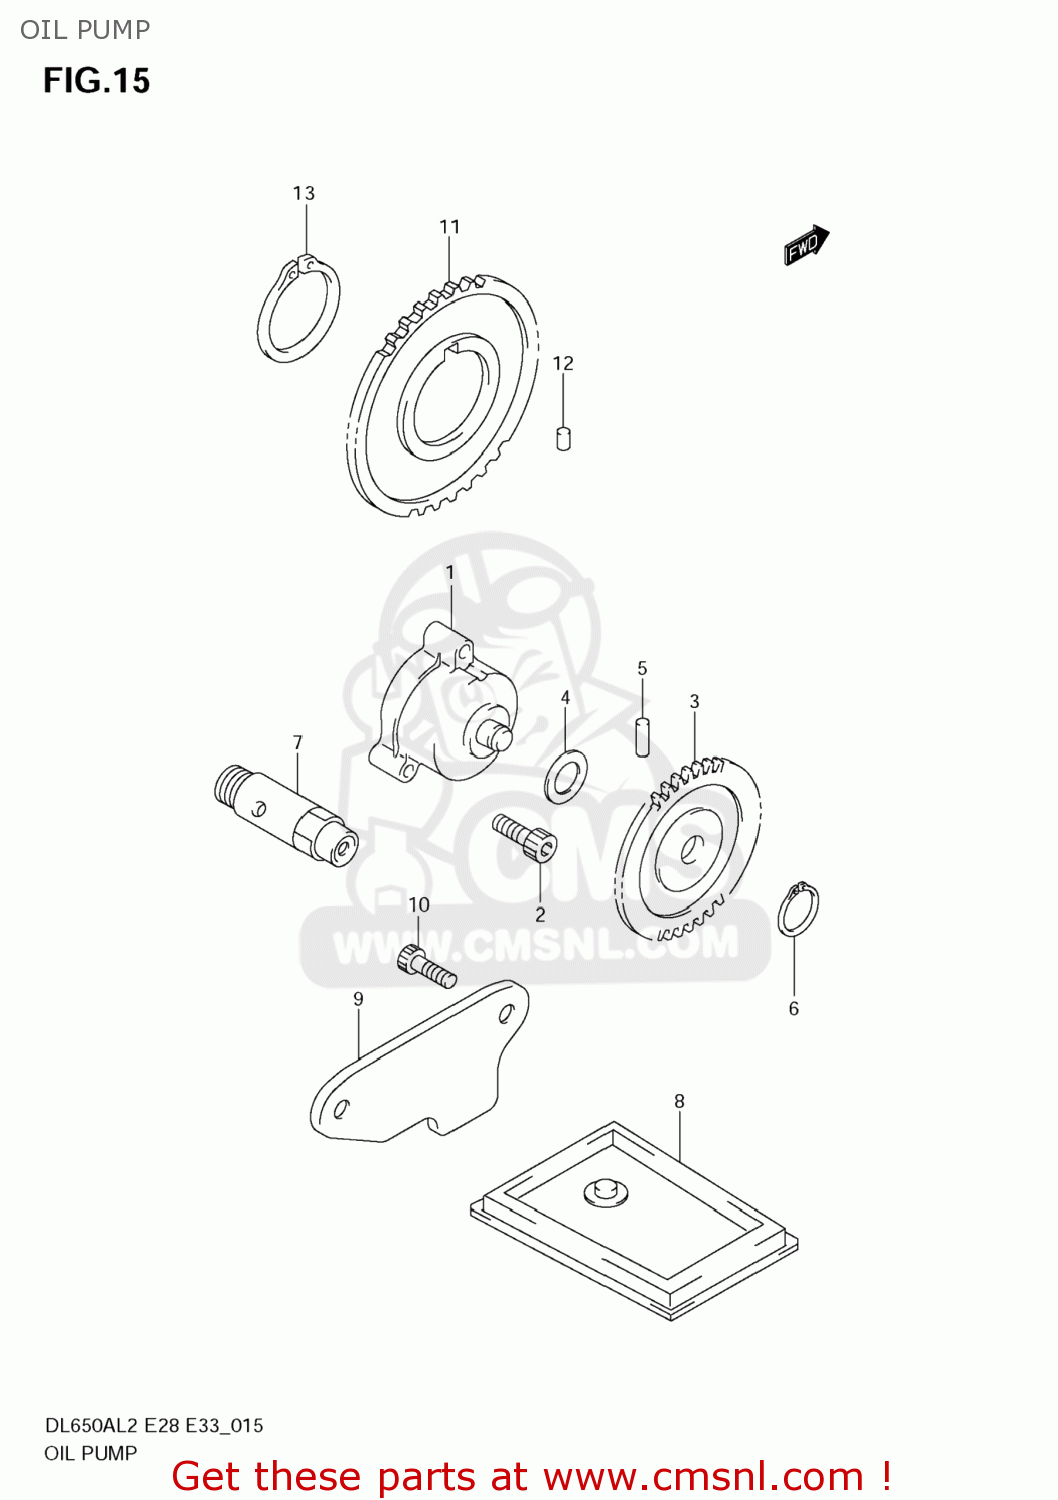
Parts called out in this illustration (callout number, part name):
1	PUMP ASSY,ENGINE OIL
2	BOLT
3	GEAR,ENG OIL PUMP DRIVEN
4	SHIM(10X18X0.5)
5	PIN(4X18.5)
6	CIRCLIP
7	VALVE ASSY,OIL RELIEF
8	STRAINER,ENGINE OIL
9	CAP,OIL STRAINER
10	BOLT
11	GEAR,ENG OIL PUMP DRIVE
12	PIN(6X6)
13	CIRCLIP
